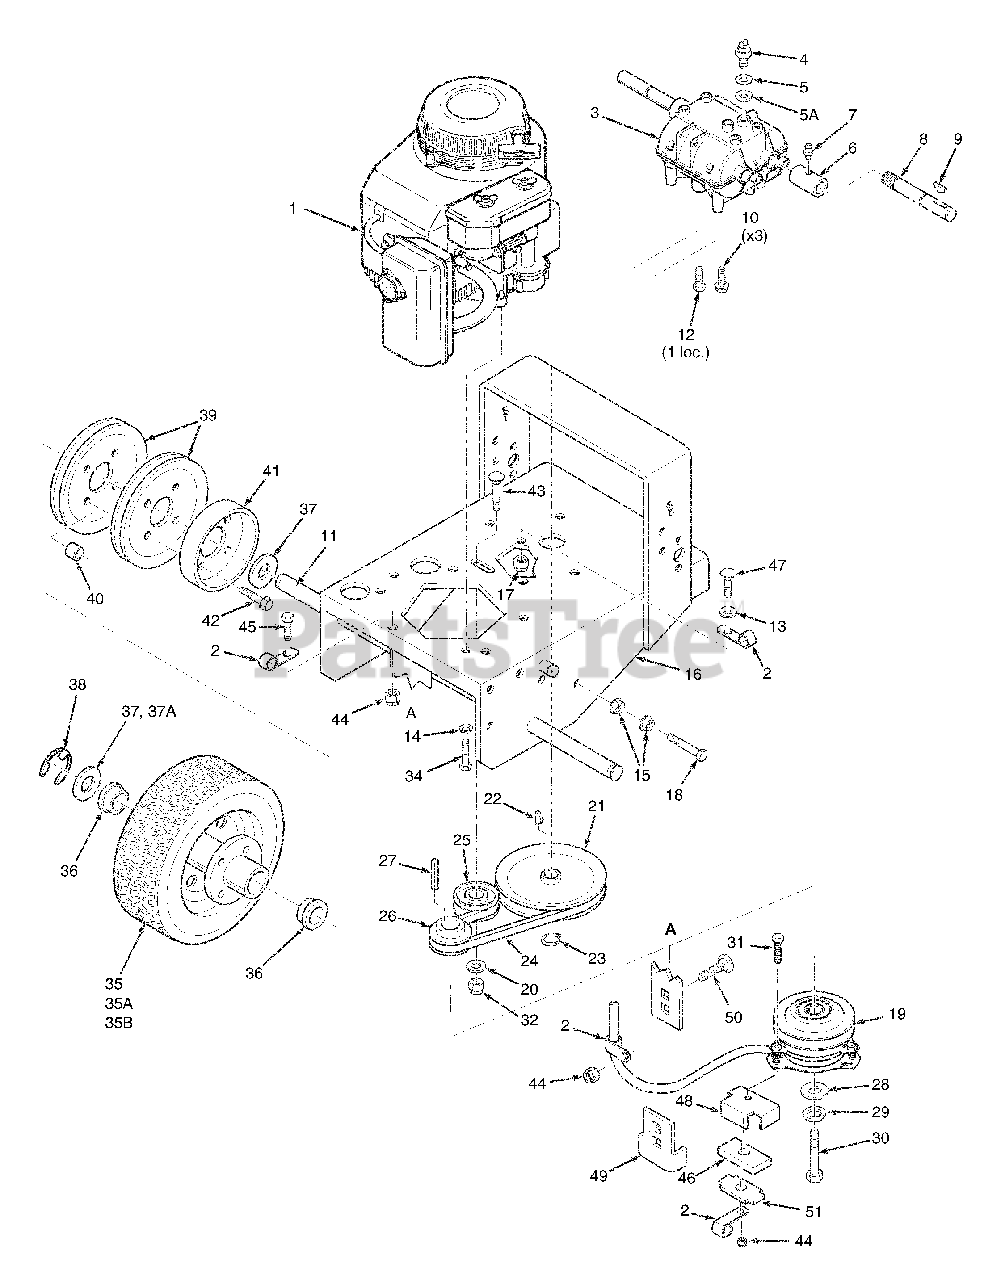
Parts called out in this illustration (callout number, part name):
1	Engine,18HP Kohler CV493T, SpecPS-27513)
2	Cable Clamp
3	Transmission, (Peerless 700-070, 9 tooth spline)
4	Neutral Safety Switch
5	Fibre Washer, thin
5A	Fibre Washer, thick
6	Coupler, Jackshaft
7	Grease Fitting, straight
8	Jackshaft
9	Key, Hi-Pro #9
10	Bolt, 5/16-18 X 3/4"
11	Wheel Axle
12	Bolt, 5/16-18 X 3/4"
13	Flat Washer 1/4" (.312
14	Lock Wshr. 5/16"
15	Nut, 3/8-16 Serrated
16	Engine Deck
17	Nut, 1/4-20 Elastic
18	Bolt, 3/8-16 x 3-3/4"
19	Electric Clutch
20	Washer, 3/8" (.391 x
21	Pulley, Transmission
22	Key, Woodruff #9
23	Retaining Ring, 5/8"
24	Belt, Transmission
25	Idler Pulley,
26	Pulley, Traction Drive
27	Key, 1/4 x 1/4 x 2-3/4"
28	Flat Washer, 7/16"
29	Lock Washer, 7/16"
30	Bolt, 7/16-20 x2-1/2" Hex Head
31	Bolt, 5/16-18 x 1-3/4" Hex Head
32	Nut, 3/8-16 Elastic Stop
34	Bolt, 5/16-18 x 1" Serrated Flange Hex Head
35	Wheel Assembly
35A	Tire, 13 x 6.50-6, 2-ply
35B	Rim & Bearing Assembly
36	Wheel Bearing (OD 2.000 - 2.005)
37	Washer, 1-1/16 x 1-3/4 x 12 ga
37A	Washer, 1-1/16 x 1-1/2 x 18 ga
38	Retaining Ring, 1" Ext.- "E"
39	Pulley, Wheel Drive
40	Spacer, Wheel Pulley
41	Brake Drum
42	Bolt, 5/16-18 x 1-1/2" Serrated flange
43	Bolt, 3/8-16 x 2" Carriage
44	Nut, 5/16-18 Elastic Stop
45	Bolt, 5/16-18 x 1" Hex Head
46	Rubber Pad, Clutch Stop
47	Bolt, 1/4-20 x 3/4" Carriage
48	Backing Plate
49	Anti Rotation Bracket
50	Bolt, 5/16-18 x 1" Carriage
51	Plate, Backing
